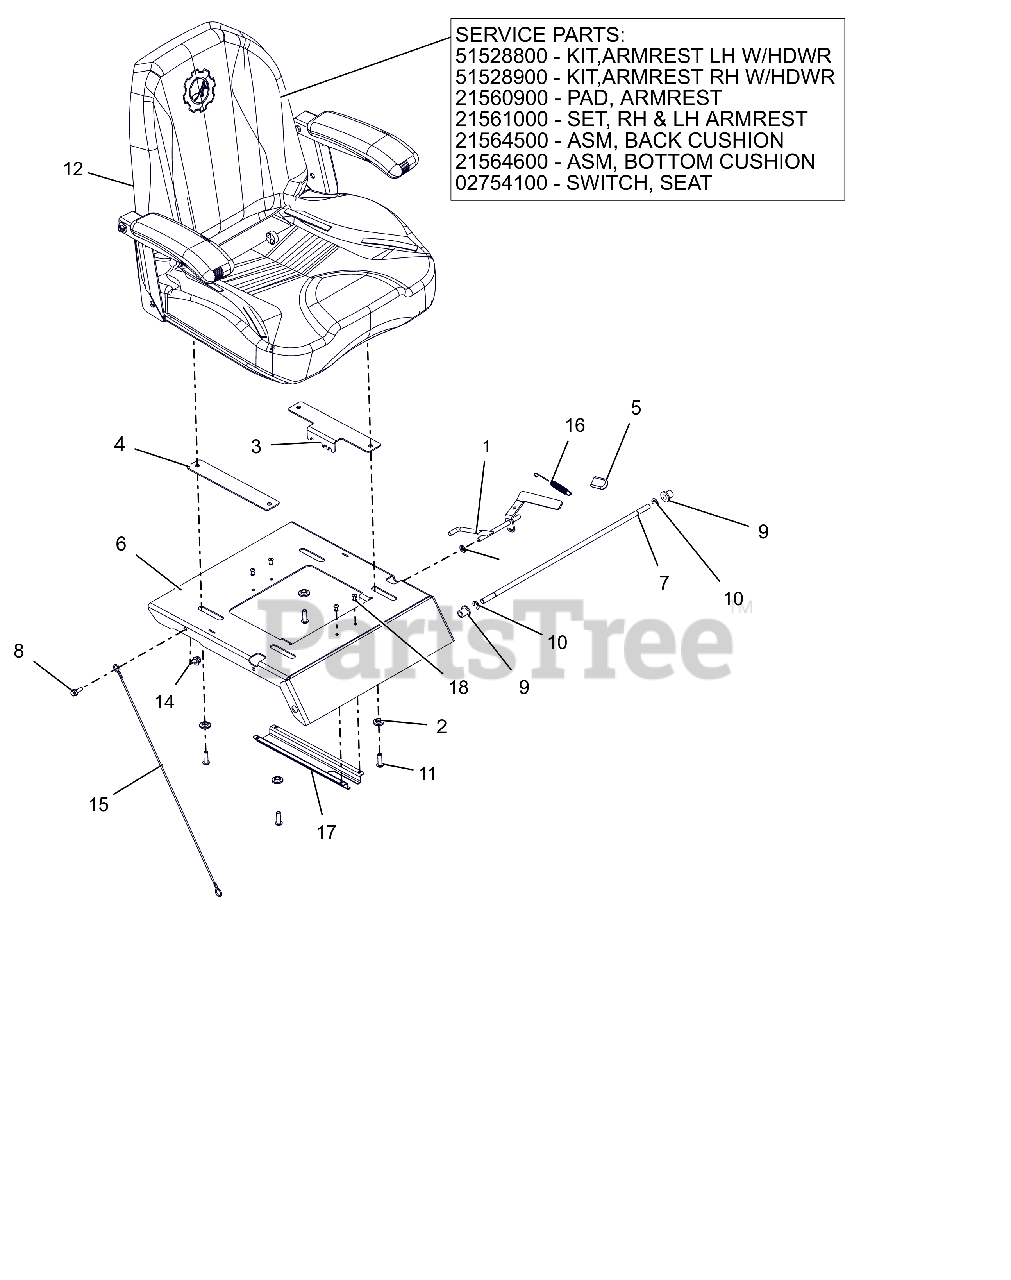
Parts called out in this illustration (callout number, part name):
1	WLDMT, ADJUSTABLE SEAT LATCH
2	BSHG, FLG .325X.499X.26X.88
3	PLATE, ADJUSTABLE SEAT TRACK
4	PLATE, ADJUSTABLE SEAT SLIDE
5	GRIP, SEAT LEVER, GREY
6	PLATE, SEAT
7	ROD, SEAT PIVOT
8	BLT,HEX-FLG .25-20X.75 G5 BFP
9	BSHG-FLG .38X.580X.667X.750
10	RG-RTNG-EXT .375X.035 TYP E
11	SCR-SKH .31-18X1.0 BTNHD YWZC
12	SEAT, IKON
12	KIT, ARMREST LH
12	KIT, ARMREST RH
12	PAD, ARMREST (HARD)
12	SET,RH & LH ARMREST -HARD
12	ASM, BACK CUSHION-ARIENS X
12	ASM, BOTTOM CUSHION-ARIENS X
12	SWITCH- SNAP MTG N.O.
13	NUT-PUSH .312
14	@NUT-LK-NYL-FLG .31-18 YWZC
15	LANYARD, SEAT CABLE .093X19.5
16	SG-TENS .043X.44X3.31 WLD 5.8
17	GUARD, SEAT SWITCH
18	RVT-POP.187X.527 DOME ST
